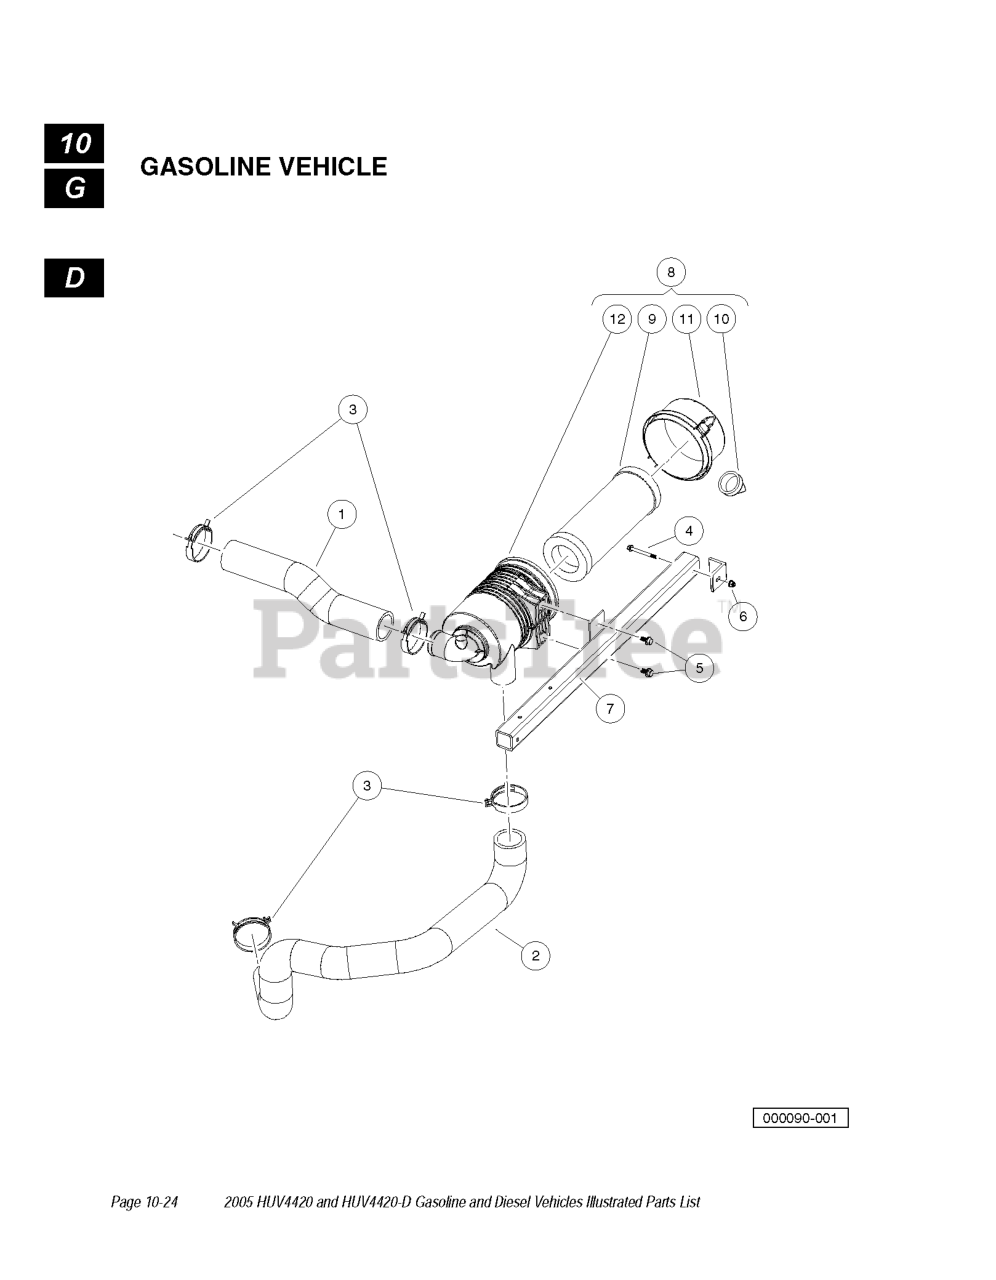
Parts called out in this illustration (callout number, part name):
1	HOSE, INTAKE, GX620
2	HOSE, INTAKE, PRIMARY
3	CLAMP, HOSE, CTB 64MM
4	BOLT-M6X1.0X65 HEX FL HD, BLK
5	BOLT FLG, M8X1.25X16 LOCTITE
6	NUT FLG, M6 X 1.0 NYLON
8	FILTER, AIR, CANISTER, 5IN
9	ELEMENT, FILTER, AIR, 5 IN
10	AIR FILTER VALVE
11	AIR FILTER CAP
